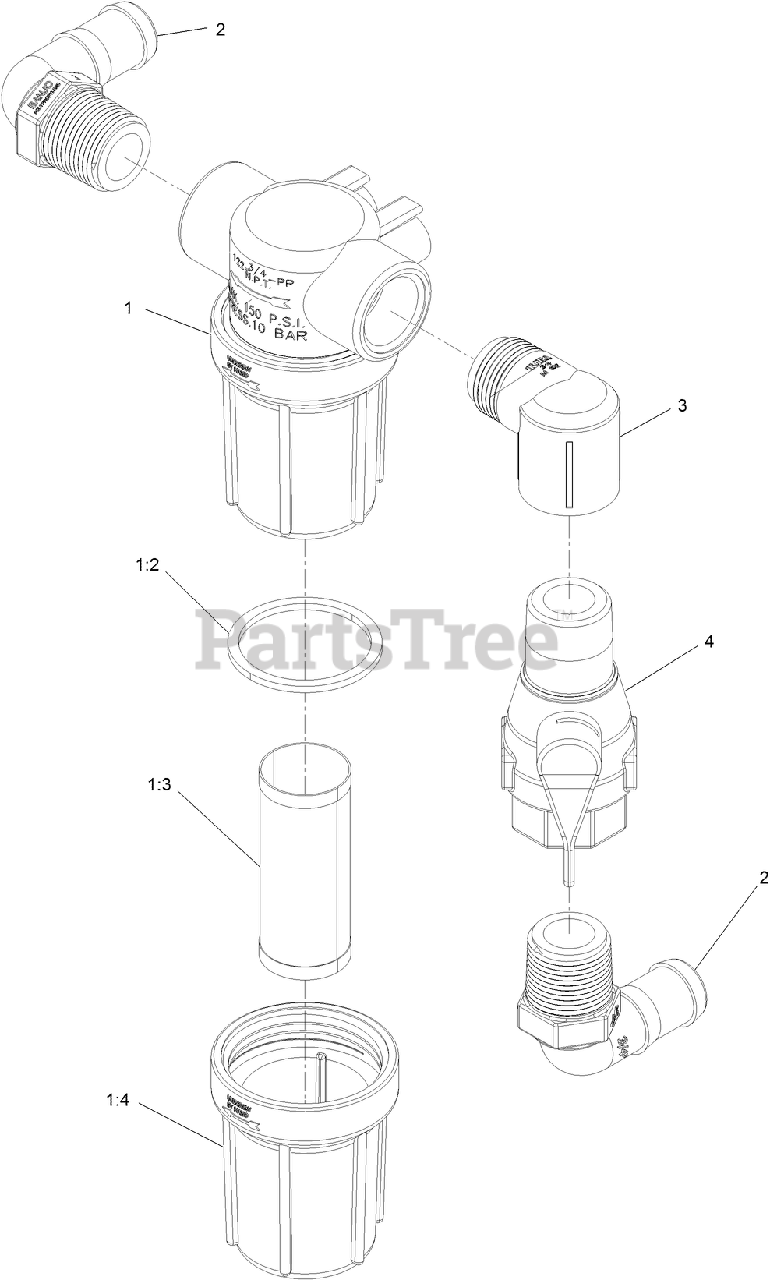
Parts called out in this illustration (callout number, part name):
1	STRAINER-LINE
1:2	GASKET-HEAD, LINE STRAINER
1:3	SCREEN-STRAINER, 30 MESH SS
1:4	BOWL-STRAINER
2	ELBOW-HOSEBARB
4	VALVE-BALL
